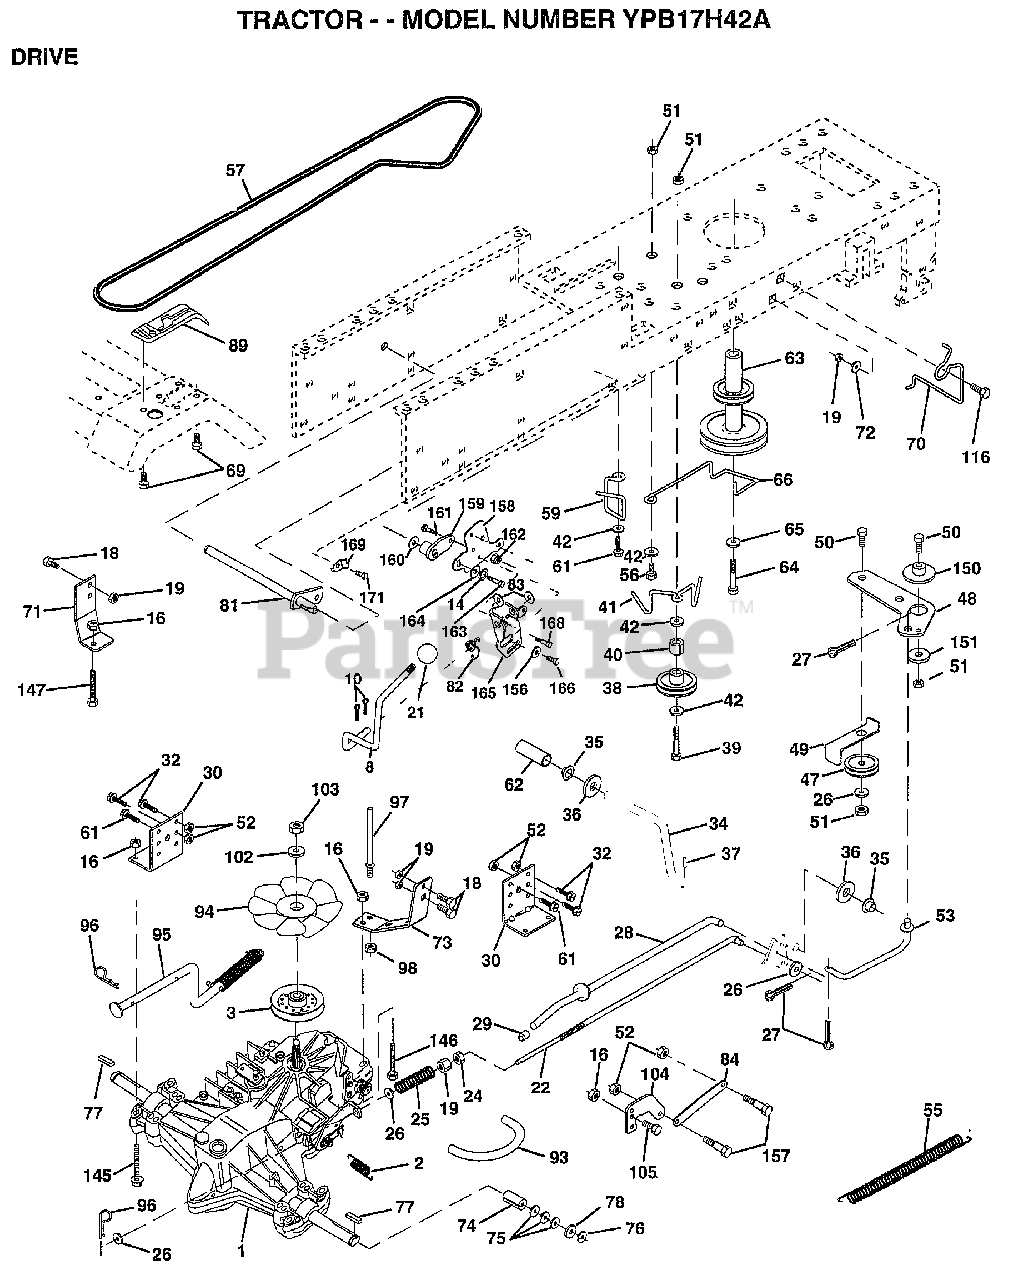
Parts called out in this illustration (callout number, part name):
1	TRANSAXLE.3100650
2	SPRING RET BRAKE
3	PULLEY.TRANSAXLE
8	ROD.SHIFT.FENDER.ADJ.LT.CRD
10	PIN COTTER 1/8
14	LOCKWASHER
15	BOLT.HX.FLG.5/16
16	NUT
18	BOLT
19	NUT
21	KNOB DLX BLK/BLK
22	ROD.BRAKE.HYDRO.
24	NUT HEX JAM 3/8-16
25	SPRING ROD LT
26	WASHER
27	COTTER PIN
28	ROD.BRAKE.PARK.LT
29	PLUNGER CAP T
30	TRANSAXLE MTG BKT
32	BOLT
34	SHAFT ASM-PEDAL F
35	NYLON BEARING
36	WASHER LT
38	FLAT IDLER PULLEY
39	BOLT
40	SPACER T
41	"KEEPER,BELT.IDLER FLAT"
42	WASHER
43	WASHER T
48	BELLCRANK.CLUTCH
49	RETAIN BELT
53	"LINK, CLUTCH T"
55	"SPRING, RETURN LT"
57	"BELT.GD DRV 82"""
59	KEEPER BELT CNTSP
61	SCREW
62	PEDAL COVER T
63	PULLEY.ENGINE
64	BOLT
65	LOCKWASHER
66	KEEPER-BELT
69	SCREW HEXWSH H-L
70	"GUIDE.BELT,RH ENG"
71	STRAP TORQ LH HYD
72	WASHER
73	"STRAP-TORQUE,RH"
74	SPACER SPLIT
75	WASHER
76	E-RING LT
77	SQUARE KEY
78	WASHER
81	SHAFT.ASM.CROSS
82	"SPRING,TORSION"
83	WASHER
84	LINK.TRANSAXLE.LT/YT
89	CONSOLE.SHIFT.LT
93	"LINE FUEL HYD 4"""
94	"FAN 7"" HYDRO"
96	RETAINER M
97	BOLT KEEPER RH
98	NUT
102	WASHER BELLEVILLE
104	ARM CONTROL HYDRO
105	SCREW CAP 5/16-18
116	BOLT RDHD 3/8-16
145	BOLT.HEX.FLGHD
146	BOLT.HEX.FLGHD.
147	BOLT.HEX.FLGHD
150	BUSHING.BELLCRANK.GRD.DR
151	WASHER
156	WASHER.SRRTD.5/16
157	"BOLT,SHOULDER"
158	BRKT.SHIFT.MOUNT
159	HUB.SHIFT
160	WASHER
161	BOLT T
164	WASHER.5/8X.281X10GA
165	BRKT.PIVOT.LEVER
166	SCREW.5/16-18X5/8
168	BOLT.SHOULDER.5/16-18X.561
169	PLATE.FASTENING
171	SCREW LT
